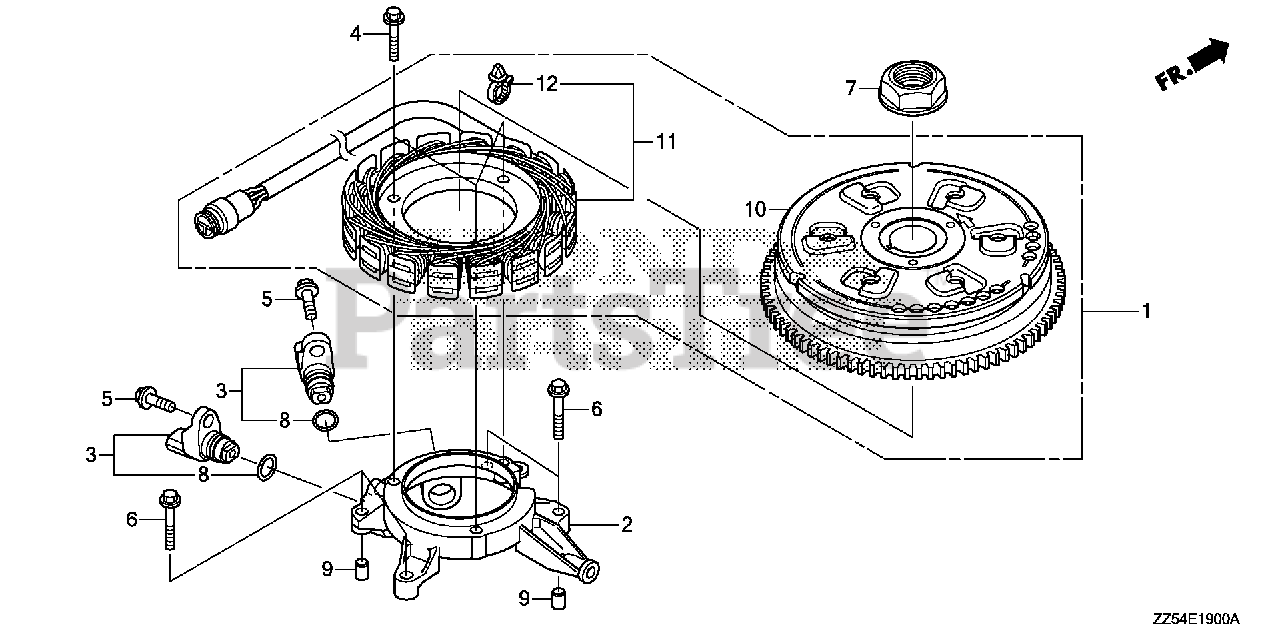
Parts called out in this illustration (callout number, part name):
1	ALTERNATOR ASSY. *TBLACK* (BLACK)
2	BRACKET, ALTERNATOR
3	SENSOR ASSY., CRANK
4	BOLT, FLANGE (6X25)
5	BOLT, FLANGE (6X16)
6	BOLT, FLANGE (6X30)
7	NUT, SPECIAL (24MM)
8	O-RING (15X1.9)
9	PIN A, DOWEL (8X10)
10	ROTOR *TBLACK* (BLACK)
12	CLIP, HARNESS BAND (96.9MM) (NATURAL)
